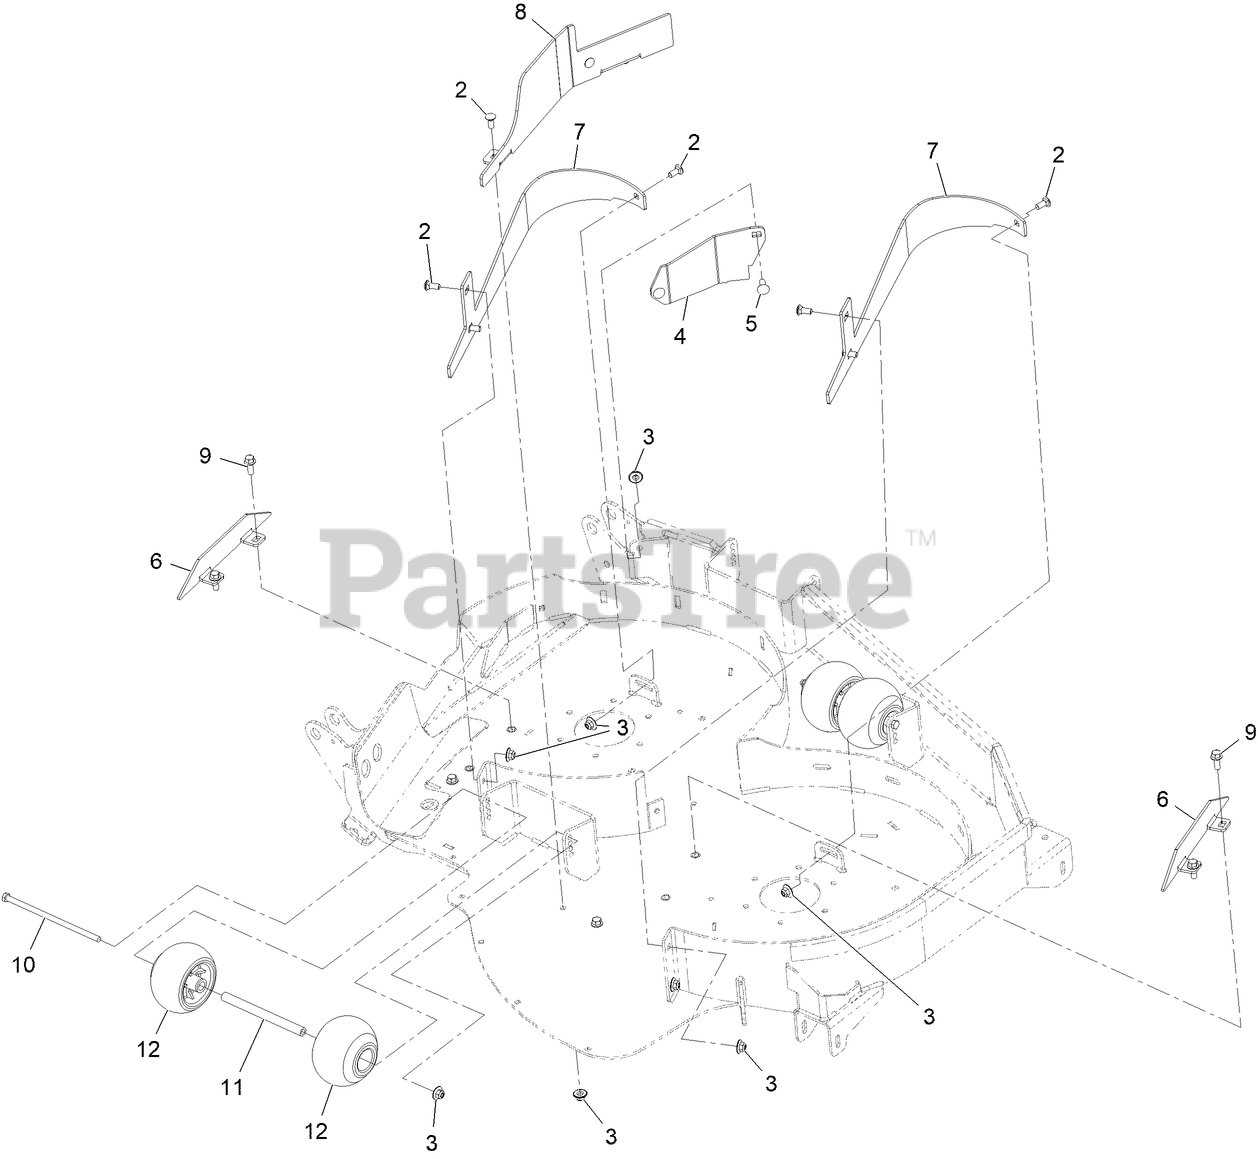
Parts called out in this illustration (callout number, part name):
2	BOLT-CARR
3	Nut-Nyloc 3/8-16 Flg
4	PLATE-FILL, LH DECK
5	BOLT-CARR
6	PLATE-BAFFLE STRAIGHT RH
7	BAFFLE-DOGLEG, OUTSIDE
8	BAFFLE-CENTER, LH
9	SCREW-HHF
10	SCREW-HH
11	SPACER-WHEEL
12	ROLLER-SCALP, ANTI
